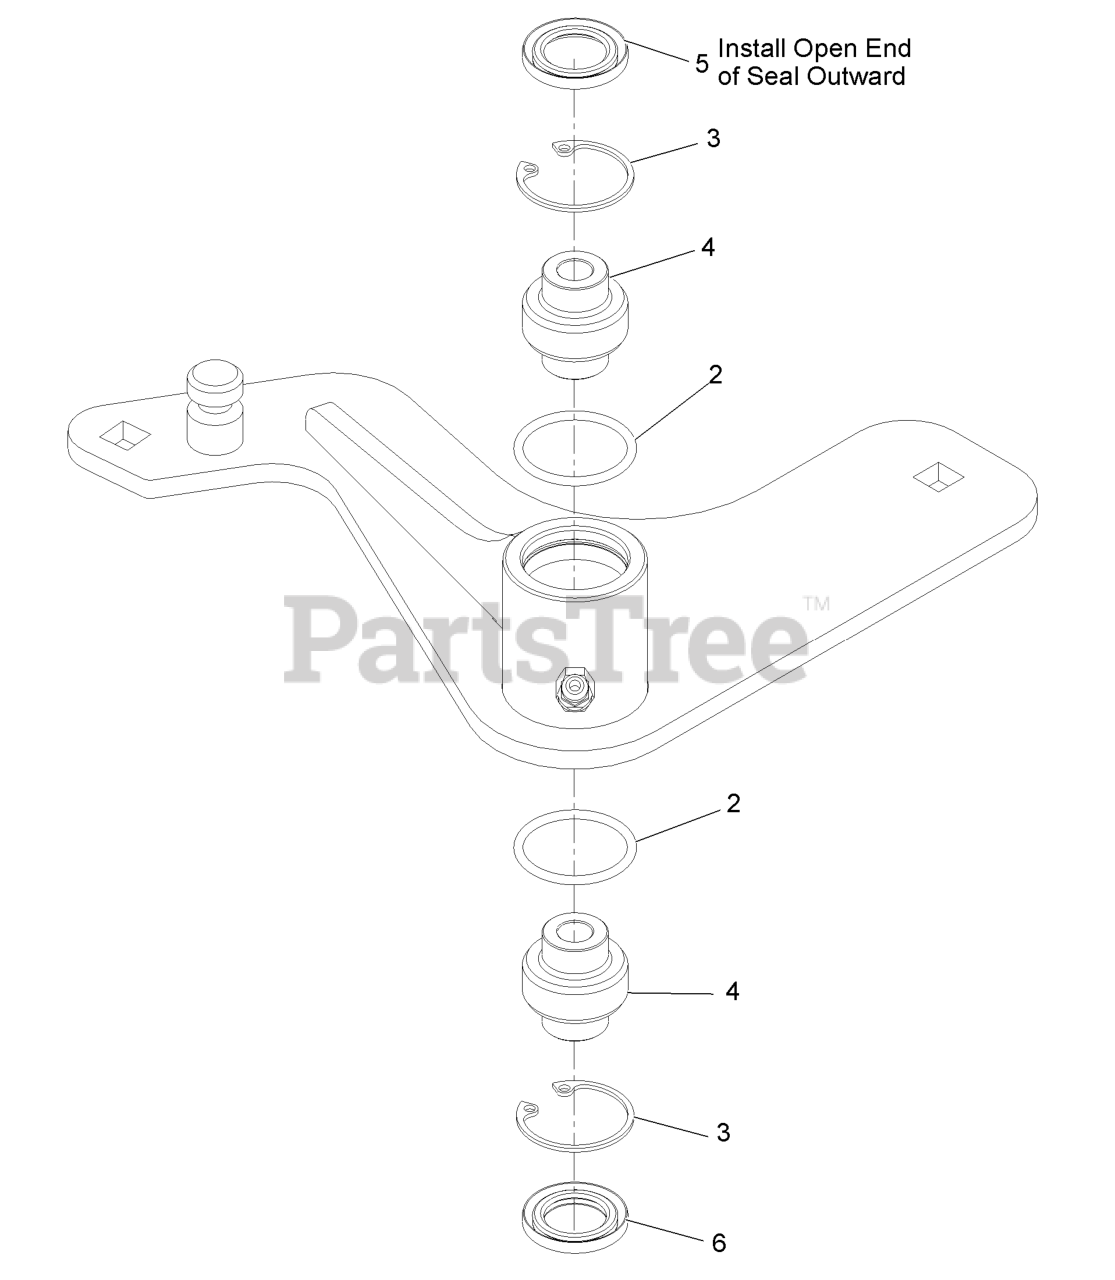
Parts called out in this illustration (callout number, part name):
3	RING-SNAP
4	BEARING-SPHERICAL
5	SEAL-LIP, SINGLE
6	SEAL-LIP, DOUBLE
